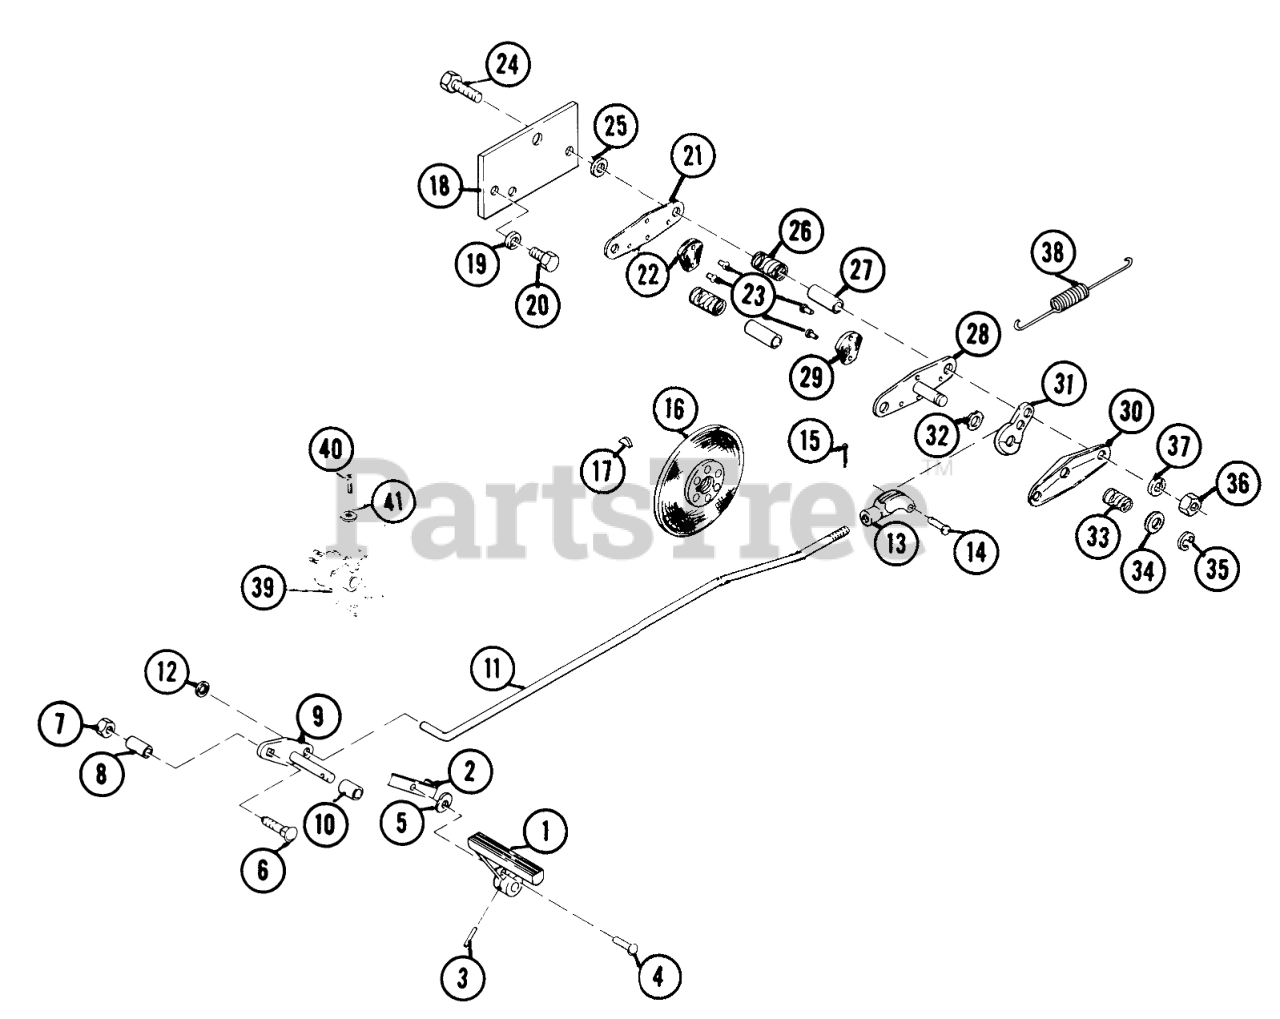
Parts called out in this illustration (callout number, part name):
6-01	Brake Pedal
6-02	Lever, Parking Brake
6-03	Spring Dowel Pin, .156 Dia. x 1.12
6-04	Rivet
6-05	Curved Washer
6-06	Carriage Bolt, 1/4-20 x 1 1/2
6-07	Locknut, 1/4-20
6-08	Spacer
6-09	Shaft Assembly
6-10	Spacer
6-11	Brake Rod
6-12	Push Nut
6-13	Clevis, Brake Rod
6-14	Clevis Pin
6-15	Cotter Pin 3/32 x 3/4
6-16	Disc Assembly
6-17	Key, 3/16 x 3/4
6-18	Mounting Plate, Brake to Transmission
6-19	Lockwasher, 3/8
6-20	Bolt, Hex 3/8-16 x 3/4
6-21	Inner Brake Pad (with Lining)
6-22	Lining, Inner Pad
6-23	Rivet
6-24	Bolt, Hex 1/4-20
6-25	Washer, 1/4 Plain
6-26	Spring, (Pad to Pad)
6-27	Bushing, Split (Pad to Pad)
6-28	Outer Brake Pad
6-29	Lining, Inner Pad
6-30	"V" Plate
6-31	Cam Lever
6-32	Washer, 5/16 x .31
6-33	Spring ("V" Plate to Pad)
6-34	Washer
6-35	Retaining Washer
6-36	Nut, 1/4-20
6-37	Lockwasher, 1/4
6-38	Spring, Linkage Return
6-39	Brake Switch
6-40	Mach. Screw #10-32 x 3/4
6-41	Lockwasher
